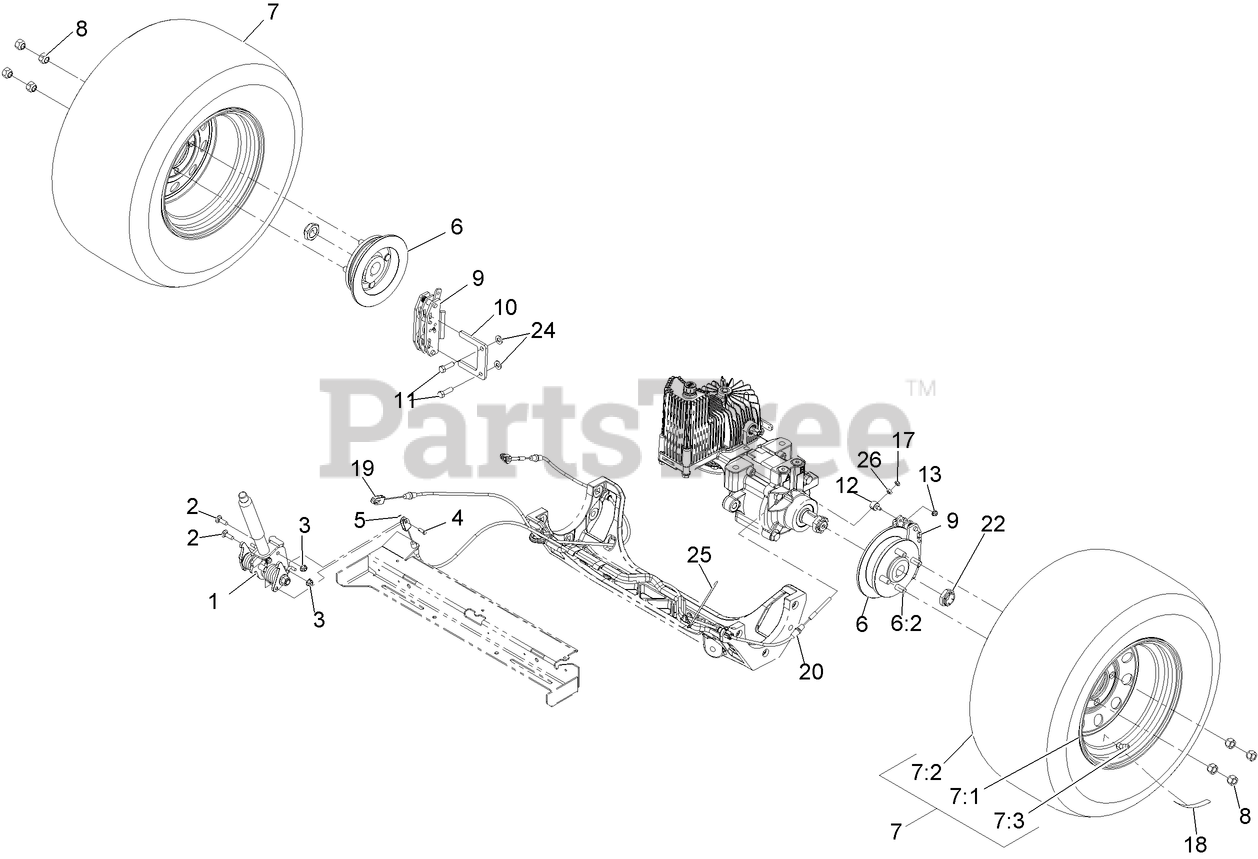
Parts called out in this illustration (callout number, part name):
1	BRAKE HANDLE ASM
2	BOLT-CARR
3	NUT-HF, NI
4	PIN-CLEVIS
5	PIN-COTTER
6	WHEEL HUB ASM
6:2	STUD-WHEEL
7	WHEEL AND TIRE ASM
7:1	RIM ASM
7:3	STEM-VALVE
8	NUT-LUG
9	CALIPER-BRAKE
10	PLATE-MOUNT, BRAKE
11	SCREW-LOCK, PATCH
12	SWIVEL
13	NUT-HF
17	NUT-LOCK, NI
18	DECAL-WHEEL NUT TORQUE
22	LOCKNUT
24	WASHER-FLAT
25	TIE-CABLE
26	NUT-HEX
